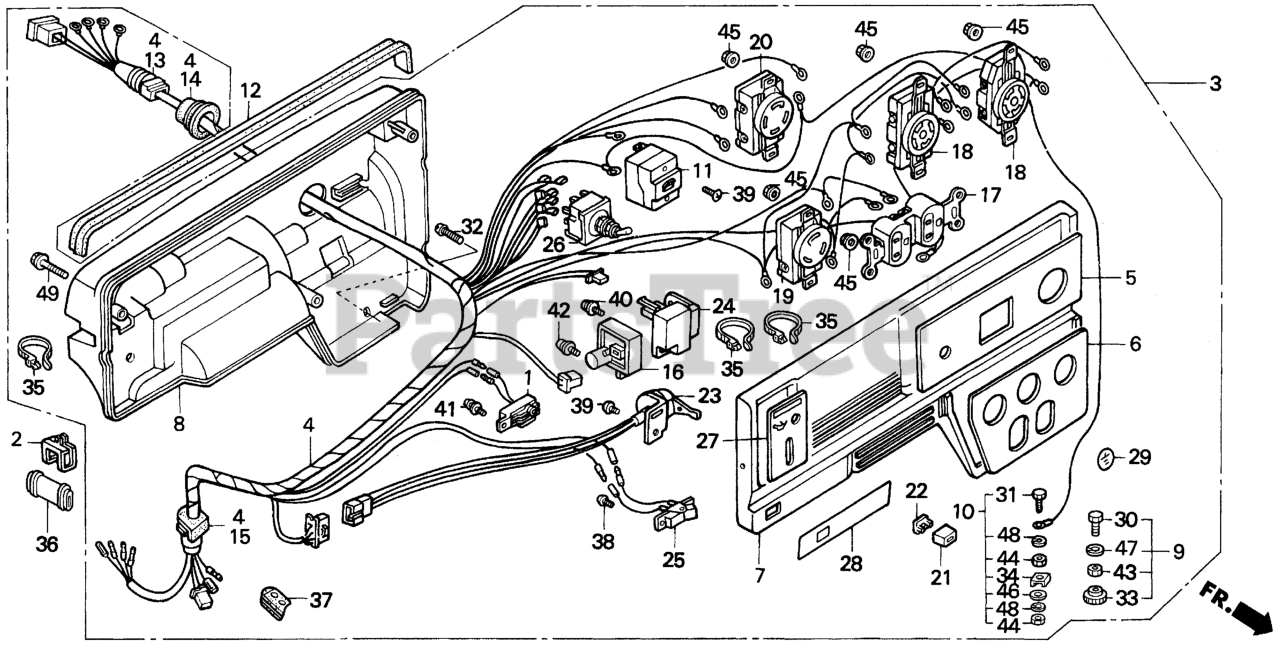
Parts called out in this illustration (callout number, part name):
1	ALERT UNIT, OIL (NOT AVAILABLE)
1	ALERT UNIT, OIL
2	CLIP, WIRE
3	BOX ASSY., CONTROL *R8* (EB-A) (BRIGHT RED)
3	BOX ASSY., CONTROL *R8* (BRIGHT RED) (NOT AVAILABLE)
3	BOX ASSY., CONTROL *R8* (BRIGHT RED)
4	WIRE HARNESS ASSY. (EB-A)
5	MARK, SWITCH PANEL (EB-A)
6	MARK, A.C. OUT (EB-A)
7	PANEL, CONTROL *R8* (EB-A) (BRIGHT RED)
7	PANEL, CONTROL *R8* (EB-A) (BRIGHT RED) (NOT AVAILABLE)
8	CASE, CONTROL *R8* (BRIGHT RED)
9	TERMINAL SET, GROUND
10	TERMINAL SET, GROUND
11	BREAKER, CIRCUIT (19A)
12	RUBBER, CONTROL
13	GROMMET, A.C. WIRE
14	GROMMET, MAIN WIRE
15	GROMMET, SWITCH WIRE
16	DIODE ASSY.
17	RECEPTACLE (20A/125V) (MATSUSHITA)
18	RECEPTACLE (20A/125V) (NOT AVAILABLE)
19	RECEPTACLE (30A/125V)
19	RECEPTACLE (3-PRONG) (30A/125V)
20	RECEPTACLE (4-PRONG) (30A/125-250V)
20	RECEPTACLE (30A/125-250V)
21	KNOB, PETCOCK LEVER
22	BUSH, CONTROL KNOB
23	SWITCH ASSY., ENGINE STOP
24	THROTTLE UNIT, AUTO (SAWAFUJI)
25	SWITCH, AUTO THROTTLE
26	SWITCH ASSY., VOLT CHANGE
27	MARK, ENGINE SWITCH
28	MARK, AUTO-THROTTLE (EB-A)
29	MARK, GROUND
30	BOLT, HEX. (6X22)
31	BOLT, HEX. (6X28)
32	SCREW, GLOVE BOX
33	NUT, SPECIAL (6MM)
34	RETAINER (6MM)
35	TIE, CABLE (NATURAL 225X5.0)
36	TUBE, CORD
37	GROMMET, TUBE
38	SCREW, PAN (3X6)
39	SCREW, PAN (4X6)
40	SCREW-WASHER (5X12)
41	SCREW-WASHER (4X10)
42	SCREW-WASHER (4X12) Use up to Engine SN 2056819.
43	NUT, HEX. (6MM)
44	NUT, HEX. (6MM)
45	NUT, FLANGE (4MM)
46	WASHER, PLAIN (6MM)
47	WASHER, SPRING (6MM)
48	WASHER, SPRING (6MM)
49	BOLT, FLANGE (6X40)
